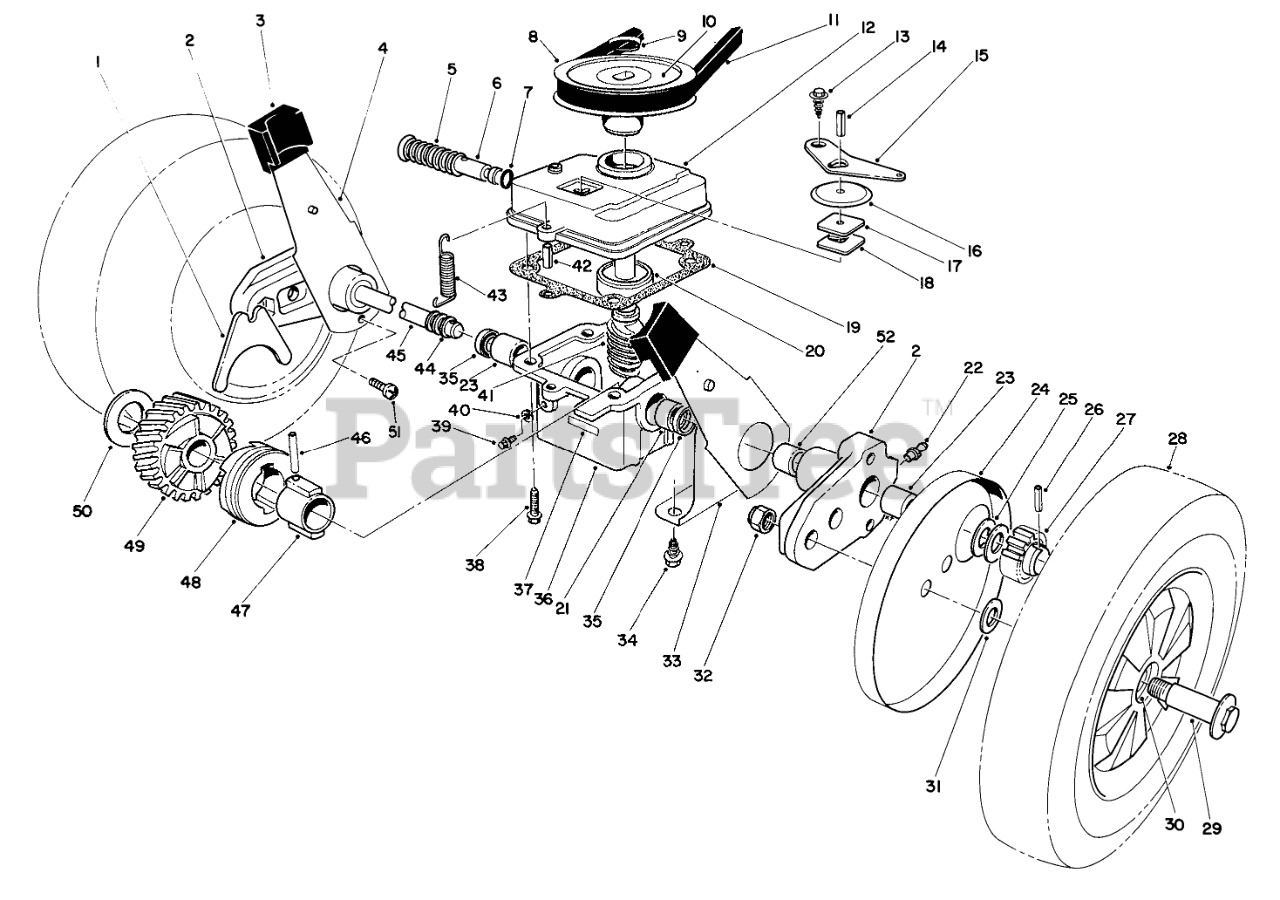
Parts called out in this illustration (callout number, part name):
1	SHIFTER FORK
2	Arm-Pivot (Incl. Ref. #22, 23 & 52)
3	KNOB-ARM
4	SPRING ARM ASSY-FRONT
5	SPRING
6	SHIFTER ROD
7	O-RING
8	PULLEY
9	PUSH-ON 93-3236
10	DECAL
11	V BELT
12	GEAR CASE COVER
13	Screw
14	SPIROL PIN H D
15	SHIFTER ARM
16	DUST COVER
17	DUST FILTER
18	LATCH PLATE
19	GASKET
20	BEARING
21	BUSHING
22	FITTING-GREASE
23	BUSHING
24	Cover-Wheel
25	THRUST WASHER
26	Pin
27	PINION GEAR 15T
28	Wheel, Tire & Gear Ass-y (Incl. Ref. #30)
29	WHEEL BOLT
30	BUSHING
31	WASHER
32	NUT-LOCK
33	END CAP
34	SCREW-HWHTF
35	SEAL-OIL
36	Gear Case (Incl. Ref. #21, 23, & 35)
37	DECAL
38	SCREW-HWHTF
39	NYLON SCREW
40	FILL PLUG GASKET
41	Worm Shaft & Gear (Incl. Ref. #49)
42	3/16 X 1/2 ROLL PIN
43	TENSION SPRING
44	COVER-SHAFT, DRIVE
45	DRIVE SHAFT
46	COIL PIN
47	SLEEVE
48	CLUTCH JAW
49	Helical Gear
50	THRUST WASHER
51	SCREW
52	BUSHING
